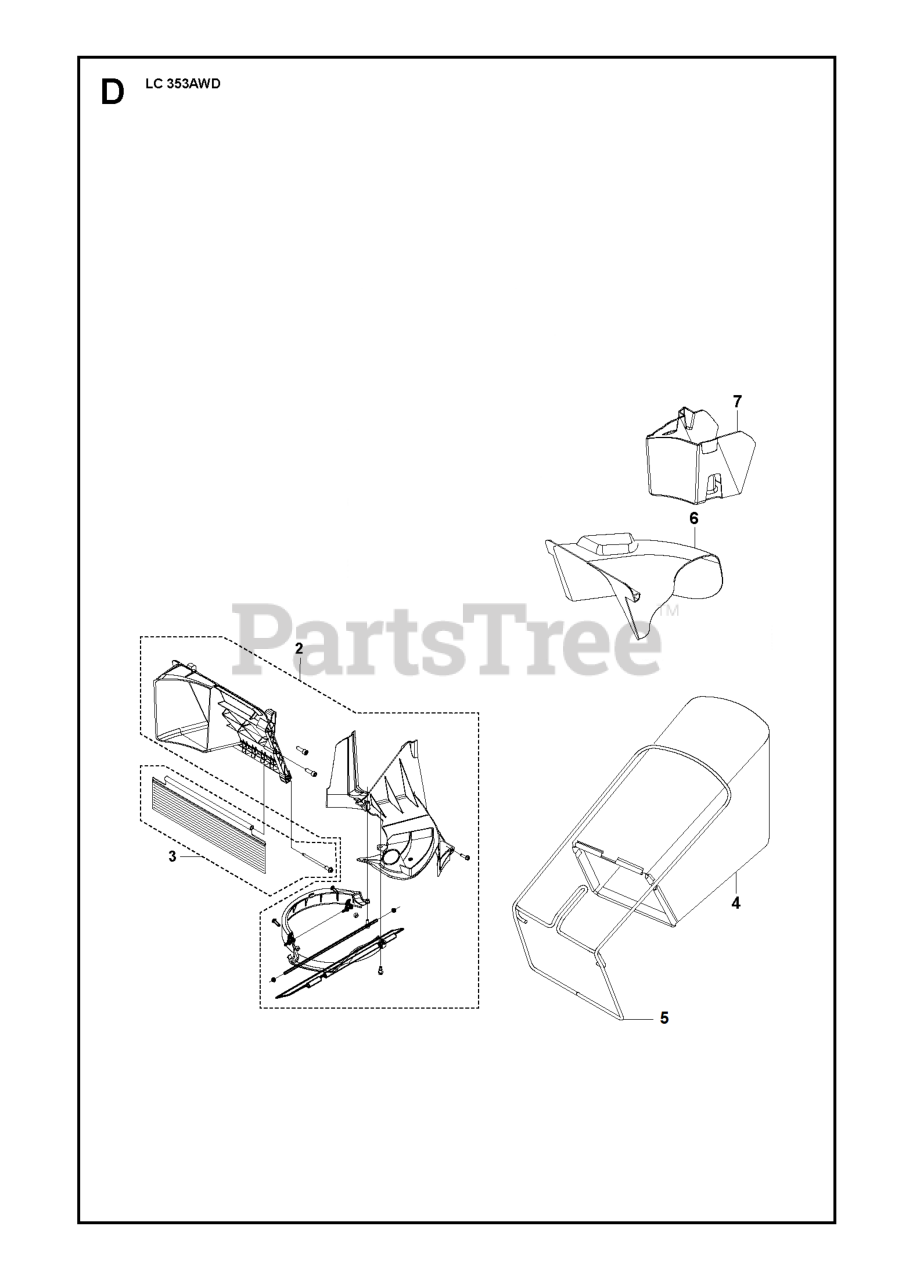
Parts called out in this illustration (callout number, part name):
4	GBAG.C361029EM.HUSQ.GRY.21EFF
6	CHUTE.DISCHARGE.21EFF.HW
7	PLUG.MULCH.21 EFF
